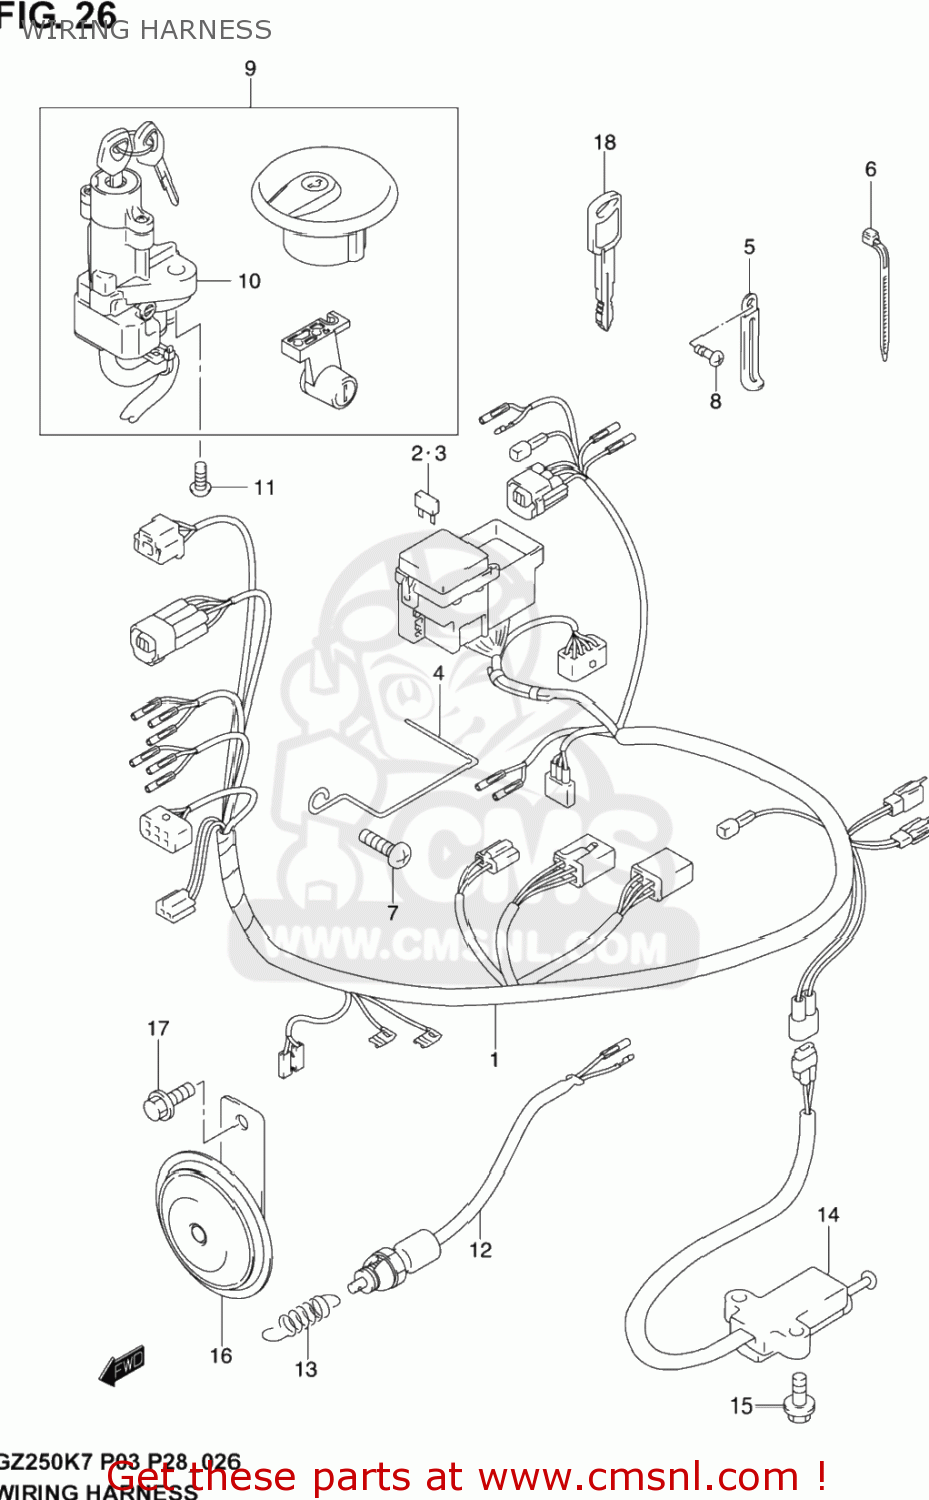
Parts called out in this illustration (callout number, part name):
1	HARNESS, WIRIN
2	FUSE(10A)
3	FUSE(15A)
4	GUIDE,HARNESS
5	CLAMP(L:45)
6	CLAMP(L:95)
7	BOLT
8	SCREW
9	LOCK SET
10	LOCK ASSY,STEERING
11	BOLT(8X20)
12	SWITCH ASSY,STOP LAMP
13	SPRING
14	SWITCH ASSEMBLY,SIDE STAND
15	BOLT
16	HORN, ASSY
17	BOLT
18	KEY,BLANK
